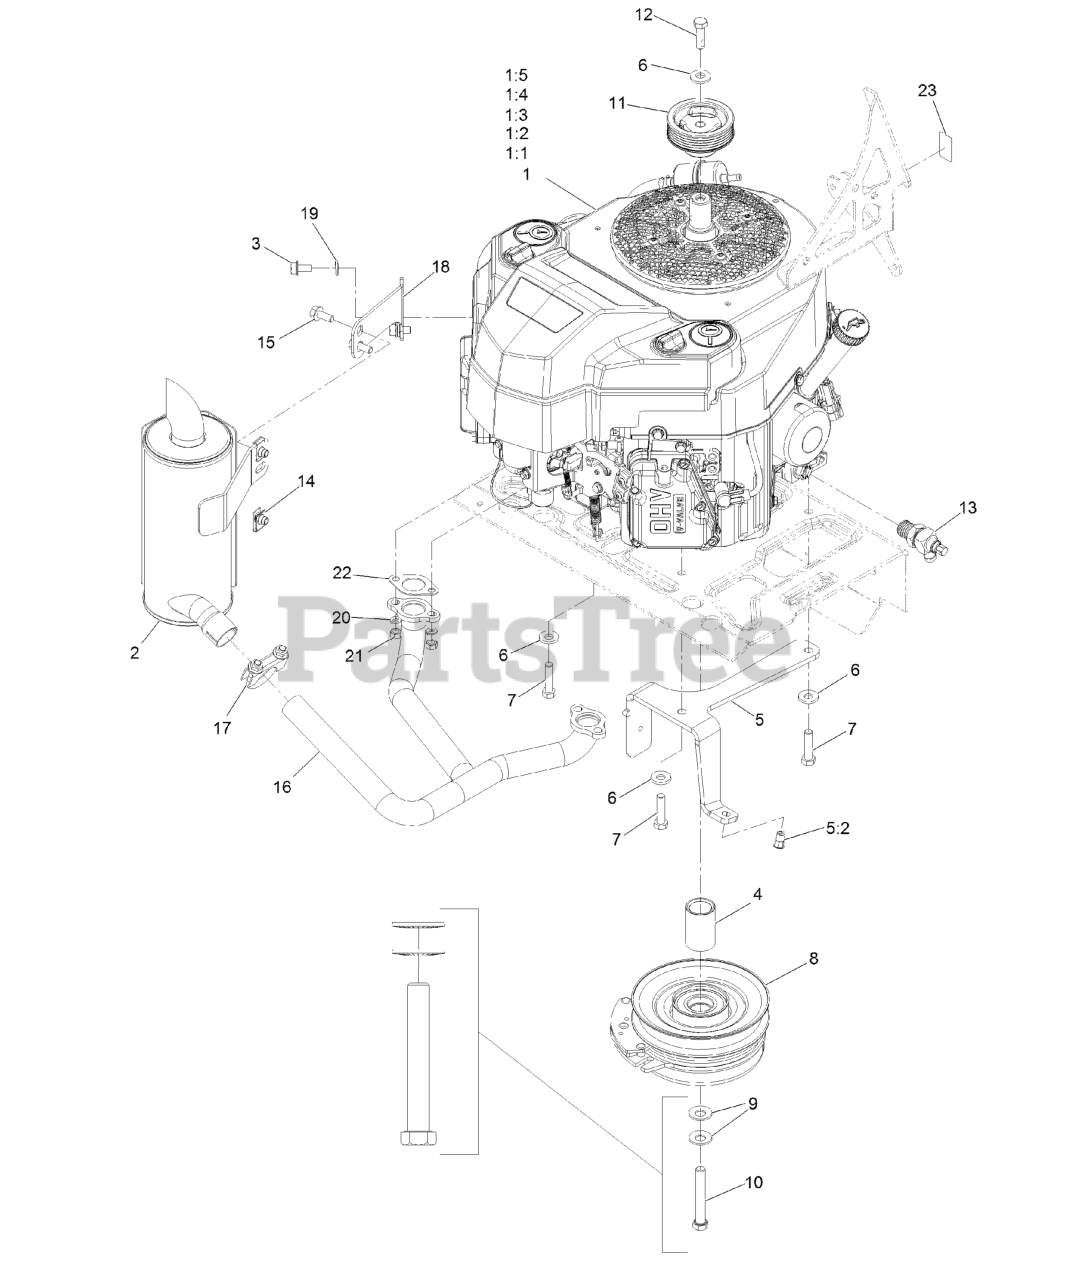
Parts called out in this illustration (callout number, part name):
1:1	Kawasaki 49065-7007 Engine Oil Filter
1:2	Kawasaki 49019-0031 Fuel Filter
1:4	Kawasaki 11013-7046 Foam Pre-Filter
1:5	Kawasaki 11013-0752 Air Filter
2	MUFFLER-VERTICAL KA
3	SCREW-HHF
4	SPACER-CLUTCH
5	ASM-CLUTCH ANCHOR W/INSERT
5:2	NUT-CLINCH,HEX
6	WASHER-BELLEVILLE
7	SCREW-HH
8	CLUTCH 105
9	WASHER-SPRING
10	SCREW-HH W/LOCTITE
11	PULLEY, CRANK
12	Screw-HH, Patch
13	DRAIN-OIL VALVE
15	SCREW-HHF
16	MANIFOLD-VERTICAL KA EXH
17	CLAMP-MUFFLER
18	BRACKET-MUFFLER VERTICAL
19	WASHER-LOCK
20	WASHER-LOCK
22	GASKET-EXHAUST
23	DECAL-10W-50 OIL
